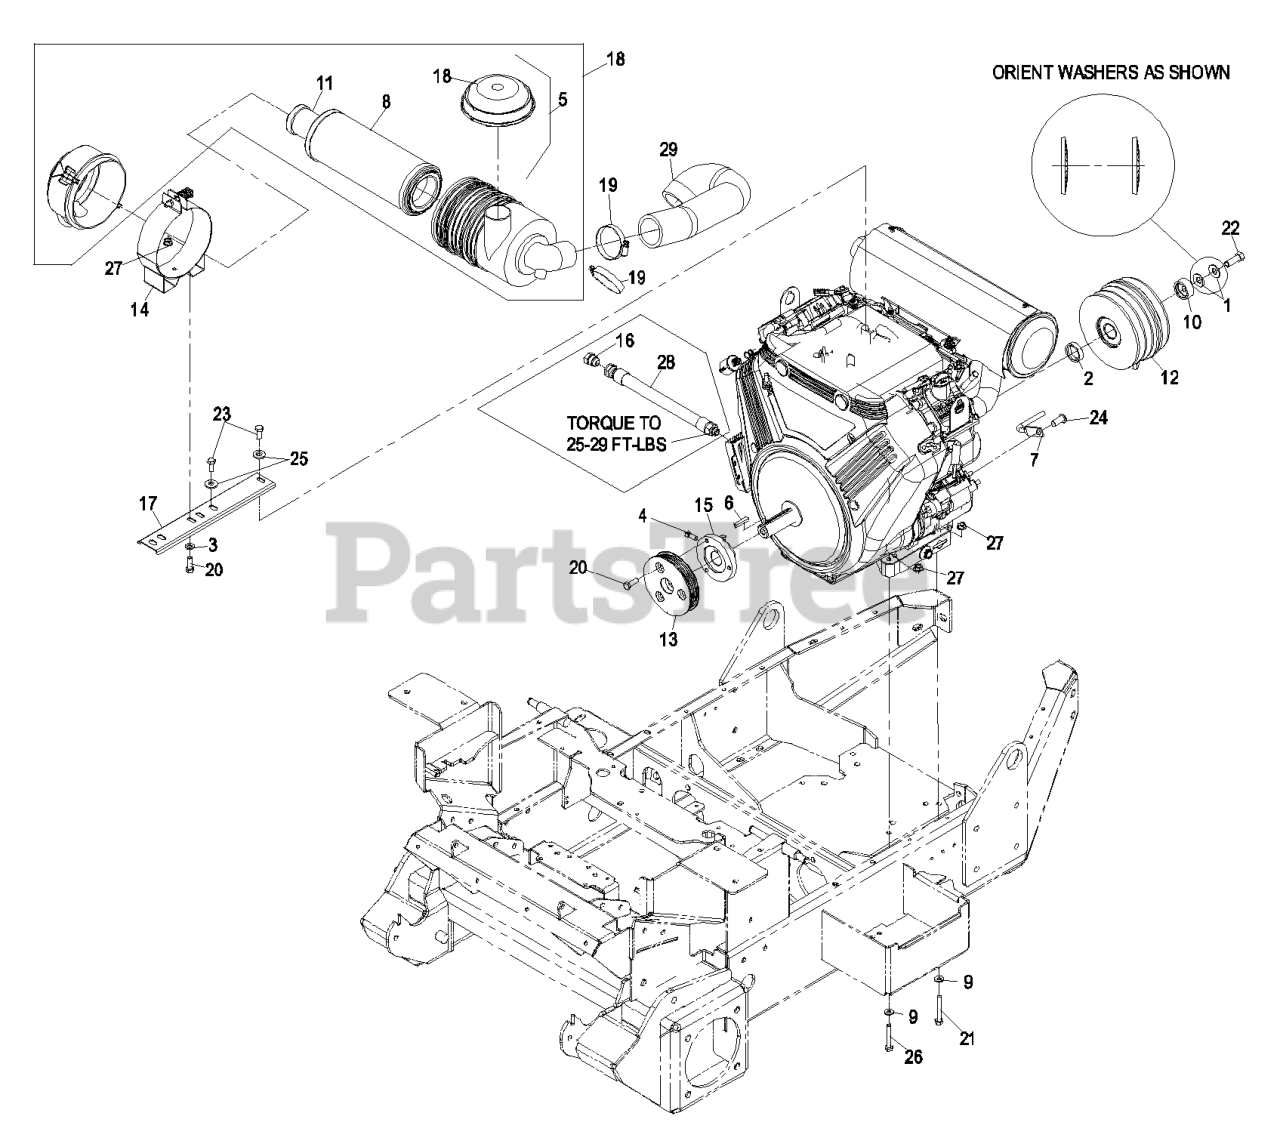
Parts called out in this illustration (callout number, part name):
1	WASHER-SPRING
2	SPACER,CLUTCH
3	WASHER-PLAIN
4	SCREW-SET
5	HOOD-CLEANER, 2" AIR INTA
6	KEY-SQUARE
7	ANCHOR,CLUTCH
8	FILTER-AIR
9	WASHER-SPRING
10	KEEPER-CLUTCH
11	FILTER-AIR, SAFETY
12	CLUTCH KIT
13	SHEAVE, 5K 4.63
14	BRACKET-FILTER, AIR
15	HUB,ADAPTER
16	PLUG
17	BRACKET,AIR CLEANER
18	FILTER-AIR
19	CLAMP-HOSE
20	SCREW-HH
21	SCREW-HH
22	SCREW-HH
23	Screw, Hh M8-1.25 X 20mm
24	SCREW-HSBH
25	WASHER-BELLEVILLE
26	SCREW-HH
28	ASM,HOSE OIL DRAIN BVG W/
29	HOSE,INTAKE
